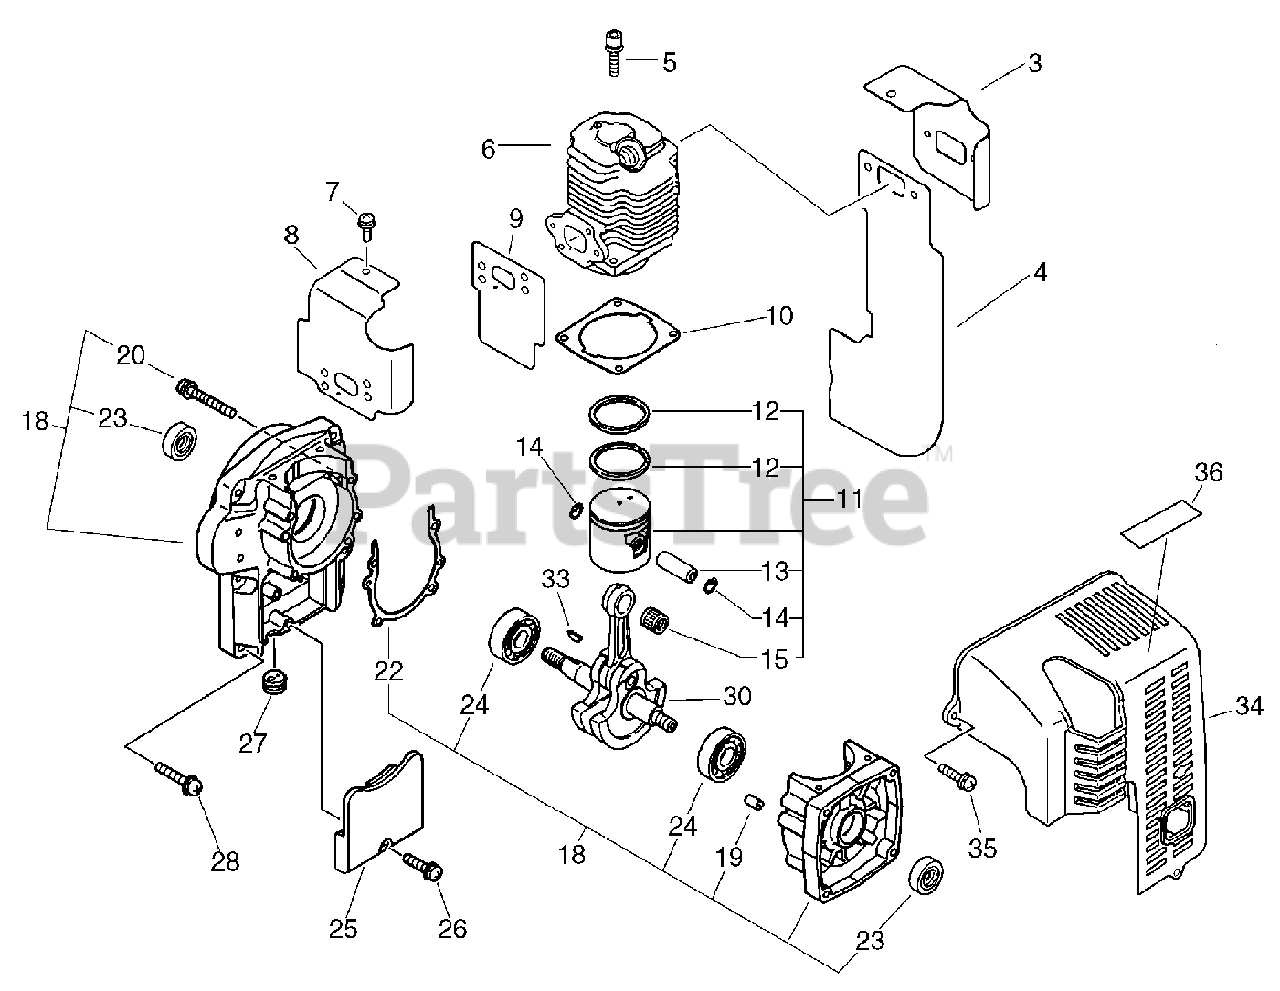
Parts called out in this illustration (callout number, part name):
3	COVER, ENGINE - EXHAUST
4	HEAT SHIELD, EXHAUST
5	BOLT 5×22
6	CYLINDER
7	SCREW 5×10
8	COVER, ENGINE - INTAKE
9	HEAT SHIELD, INTAKE
10	GASKET, CYLINDER
11	PISTON KIT
12	RING, PISTON
13	PIN, PISTON
14	RING, SNAP Ø10
15	BEARING, NEEDLE
18	CRANKCASE KIT
19	PIN, LOCATING 4×8
20	SCREW 5×40
22	GASKET, CRANKCASE
23	SEAL, OIL
24	BEARING, BALL 6202
25	COVER, DUST
26	SCREW 5×18
28	SCREW 5×25 SUS
30	CRANKSHAFT ASSY
33	KEY, WOODRUFF 3×14
34	COVER, ENGINE
35	SCREW 5×20
36	LABEL, CAUTION - HOT
